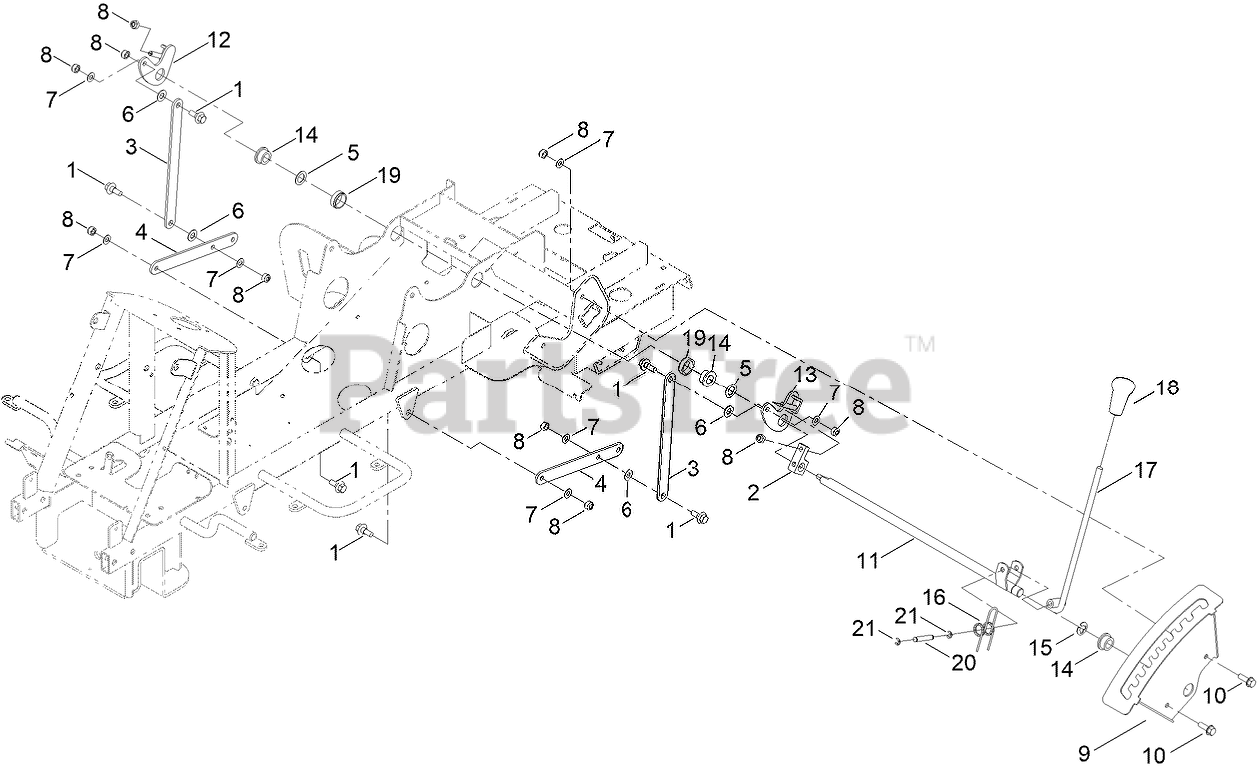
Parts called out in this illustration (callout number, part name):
1	BOLT, FLANGE
2	DECK LIFT, PIVOT ARM
3	PLATE, CONNECTION (LONG)
4	PLATE, CONNECTION (SHORT)
5	WASHER
6	WASHER-PLAIN
7	WASHER-PLAIN
8	NUT-HEX, NI
9	HOC, GATE
10	SCREW-HHF
11	ROD, HOC DECKLIFT
12	BRACKET, DECK LIFT (RH)
13	BRACKET, DECK LIFT (LH)
14	BUSH, HOC SHAFT
15	CLIP, HOC SHAFT
16	SPRING, HOC LEVER
17	HOC LEVER ASM
18	HOC, GRIP
19	BUSH, HOC SHAFT
20	SHAFT, HOC LEVER
21	CLIP, HOC LEVER SHAFT
